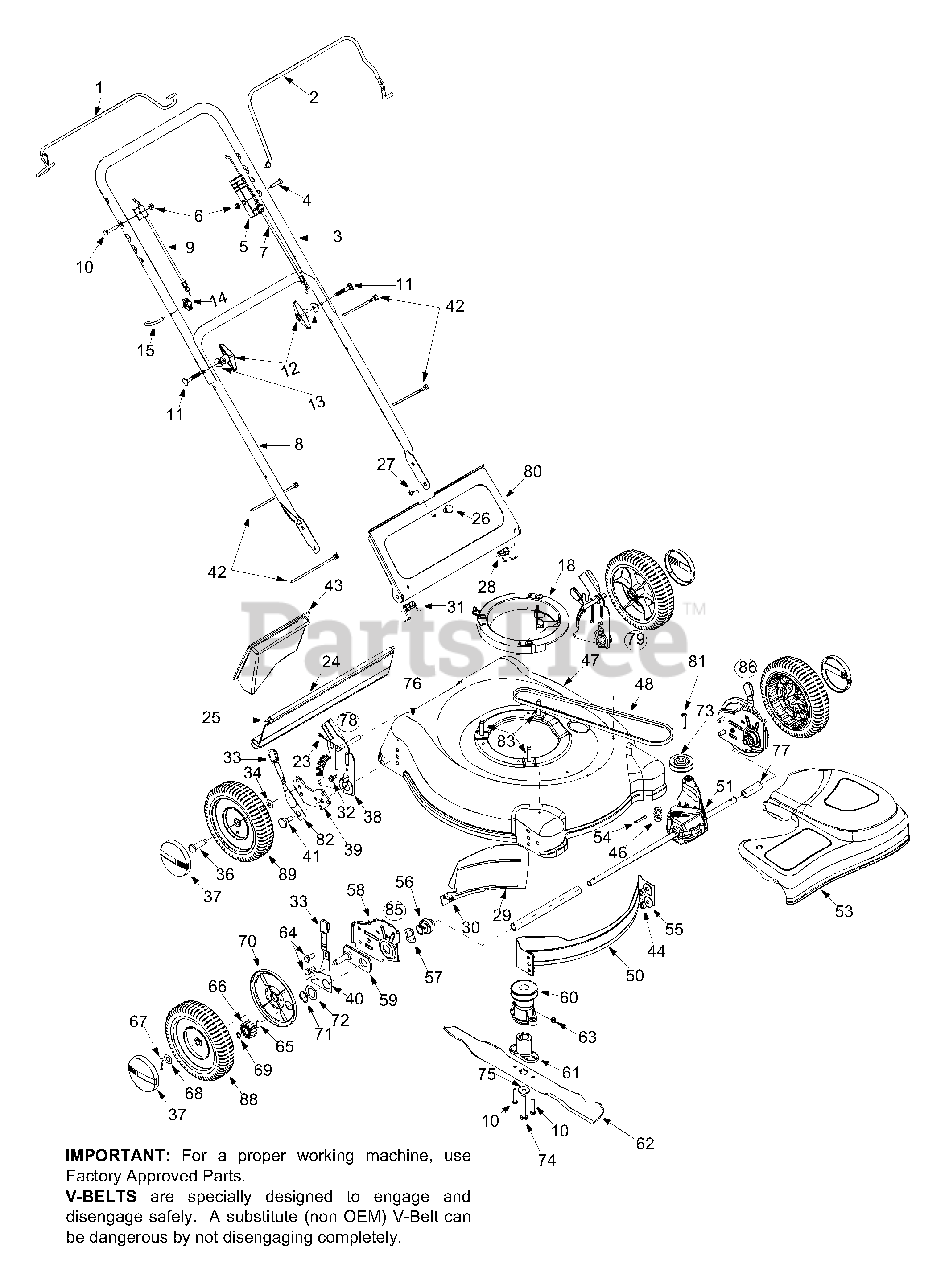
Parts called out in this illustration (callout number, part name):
5	Control Housing
6	Hex Lock Nut 1/4-20
7	Control Cable: 55"
9	Drive Cable
10	Hex Screw 1/4-20 x 1.5"
11	Carriage Bolt
12	Handle Knob
13	Saddle Washer
14	Wing Nut
15	Rope Guide
18	Engine Spacer Assembly
23	Hairpin Clip
24	Rear Trail Shield
25	Wire: Trail Shield
27	Scr. Tr. Mach. #10-24 x 0.380"
28	Torsion Spring LH
30	Scr. AB 1/4-14 x 0.625"
31	Torsion Spring RH
32	Hex Scr. w/ Wash. 1/4-14 x 0.62"
33	Knob
34	Bell Washer .375 x .870
36	Shoulder Screw
37	Hubcap:Radial Sprocket Yellow
38	Handle Bracket Assembly LH
39	Pivot Bar LH
40	Front Lever RH
41	Shoulder Screw
42	Cable Tie
43	Mulch Plug
44	Hex Nut
46	Belt Tension Spring
53	Front Drive Cover: Yellow
54	Roll Pin
55	Bell Washer
56	Bearing Support
57	Wave Washer
59	Pivot Plate Assembly
60	Drive Pulley
61	Blade Adapter
62	Mulching Blade w/ Star: 21"
63	Hex Lock Nut
64	Hex Screw
65	Dowel Pin
66	Gear 14T RH
67	Hairpin Clip
68	Flat Washer
69	Snap Ring
70	Wheel Dust Cap
71	Snap Ring
72	Washer DD 1.5" O.D.
73	Input Pulley
74	Hex Bolt
75	Bell Washer
77	Slev. Spacer LH
78	Handle Brkt Assembly RH Compl.
79	Handle Brkt Assembly LH Compl.
82	Torsion Spring
83	Spring Lever
85	Height Adj. Assembly RH Compl.
86	Height Adj. Assembly LH Compl.
88	Front Wheel Complete, 8x2 Black
89	Rear Wheel Complete, 8X2
